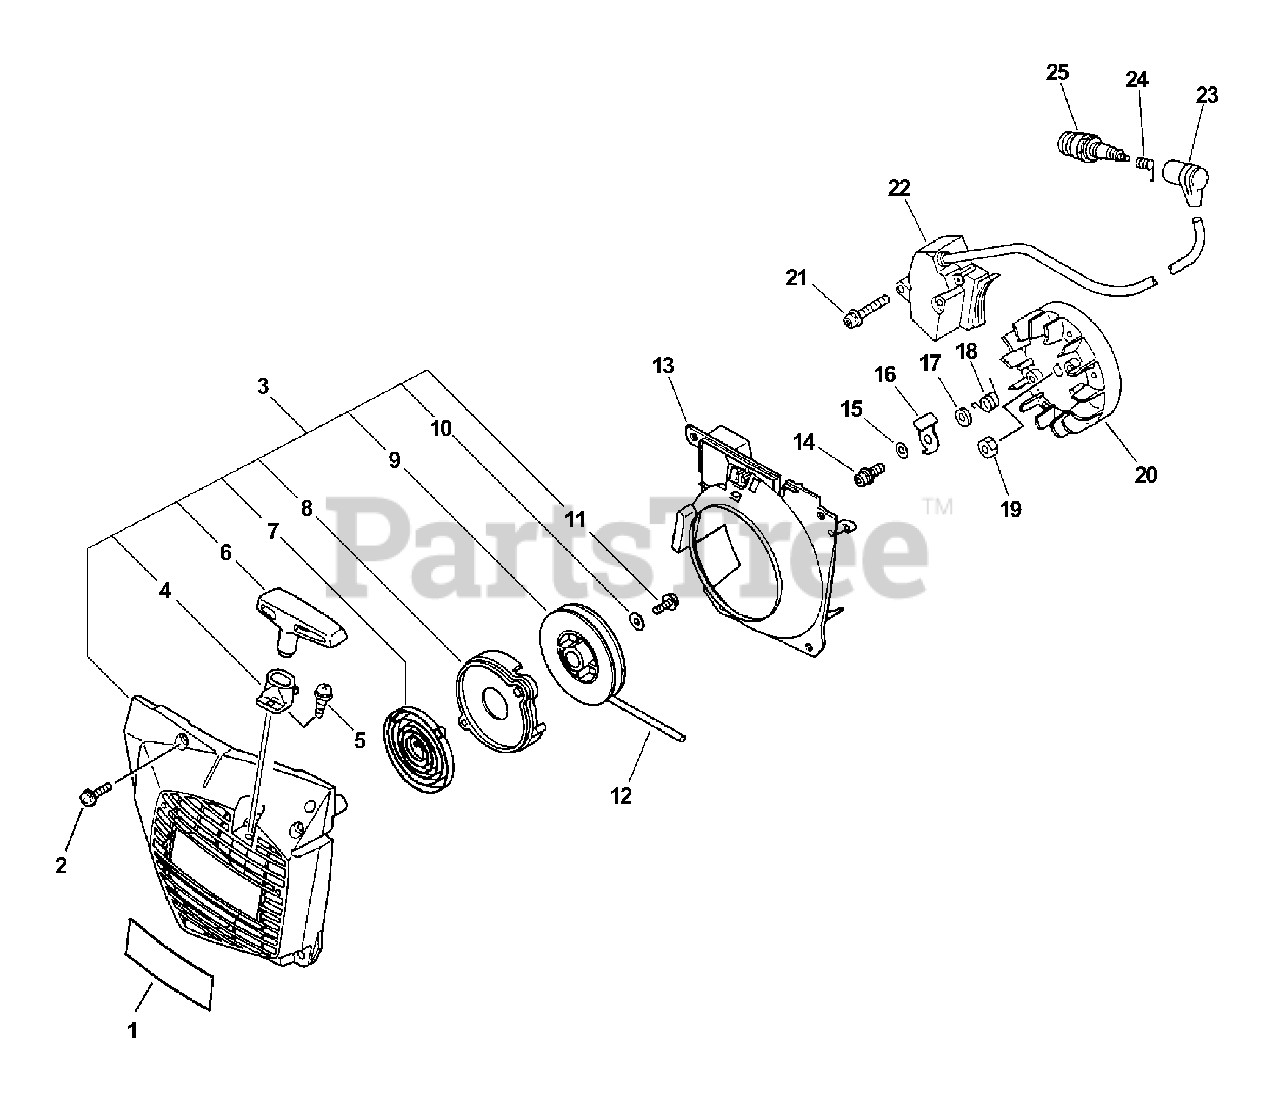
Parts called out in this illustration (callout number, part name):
1	LABEL - ECHO
2	SCREW - 5X18
3	STARTER ASSY
4	GUIDE, ROPE
5	SCREW - 3X14
6	GRIP, STARTER
7	SPRING, REWIND
8	PLATE, STARTER
9	REEL, ROPE
10	WASHER - 5
11	SCREW - 5X12
12	ROPE, STARTER - 3.5X960
13	COVER, FAN
14	SCREW - 5X14
15	WASHER - 5
16	PAWL, STARTER
18	SPRING, RETURN
19	NUT - 8 -- FLANGE
20	FLYWHEEL
21	SCREW - 4X30
22	COIL, IGNITION
23	CAP, SPARK PLUG
24	TERMINAL, SPARK PLUG CAP
25	SPARK PLUG -- BPM-7A
25	SPARK PLUG -- RCJ-6Y
